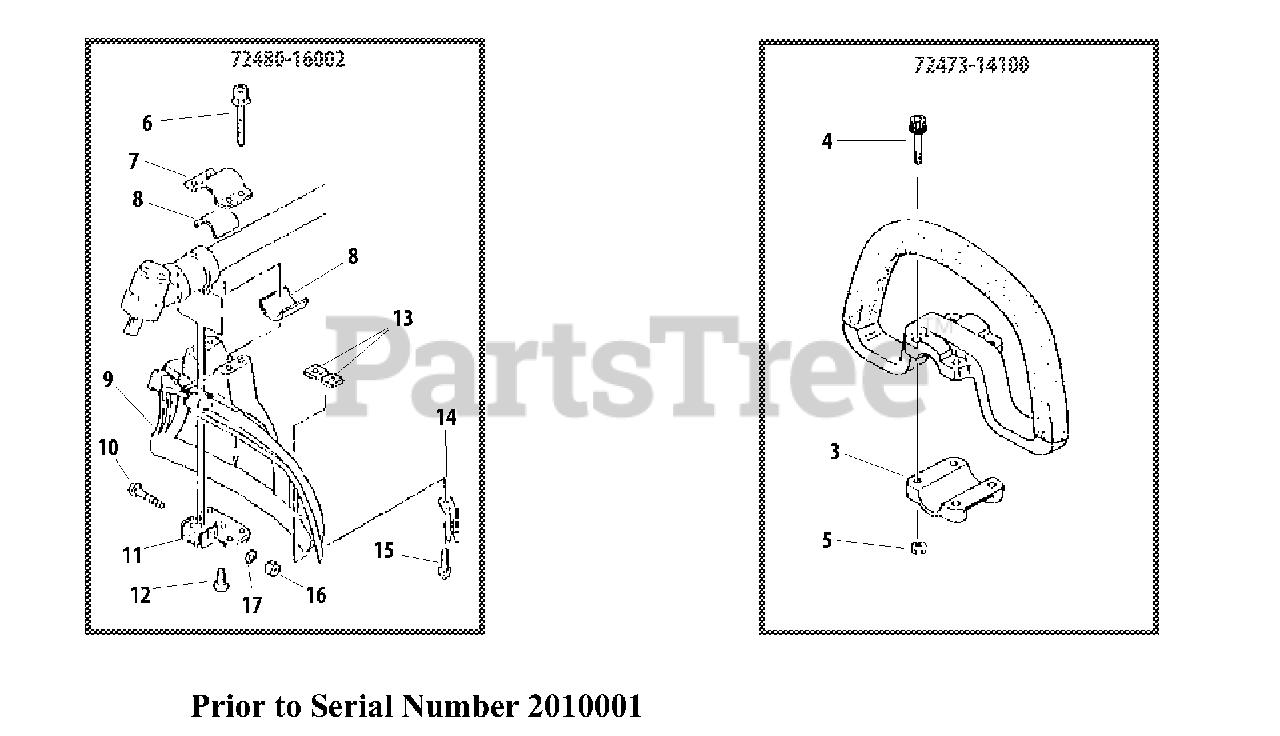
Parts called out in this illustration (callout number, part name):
3	BRACKET, MOUNTING
5	NUT M5
6	BOLT M5×45
7	CLAMP, UPPER
8	SPACER
9	SHIELD, DEBRIS
10	BOLT M5×35
11	PLATE, SHIELD MOUNTING
12	SCREW HILO 4×10
13	NUT M5
14	CUTTER
15	BOLT M5×16
16	NUT M5
17	WASHER 5 MM
72473-14100	HANDLE ASSY, FRONT
72480-16002	GUARD ASSY
